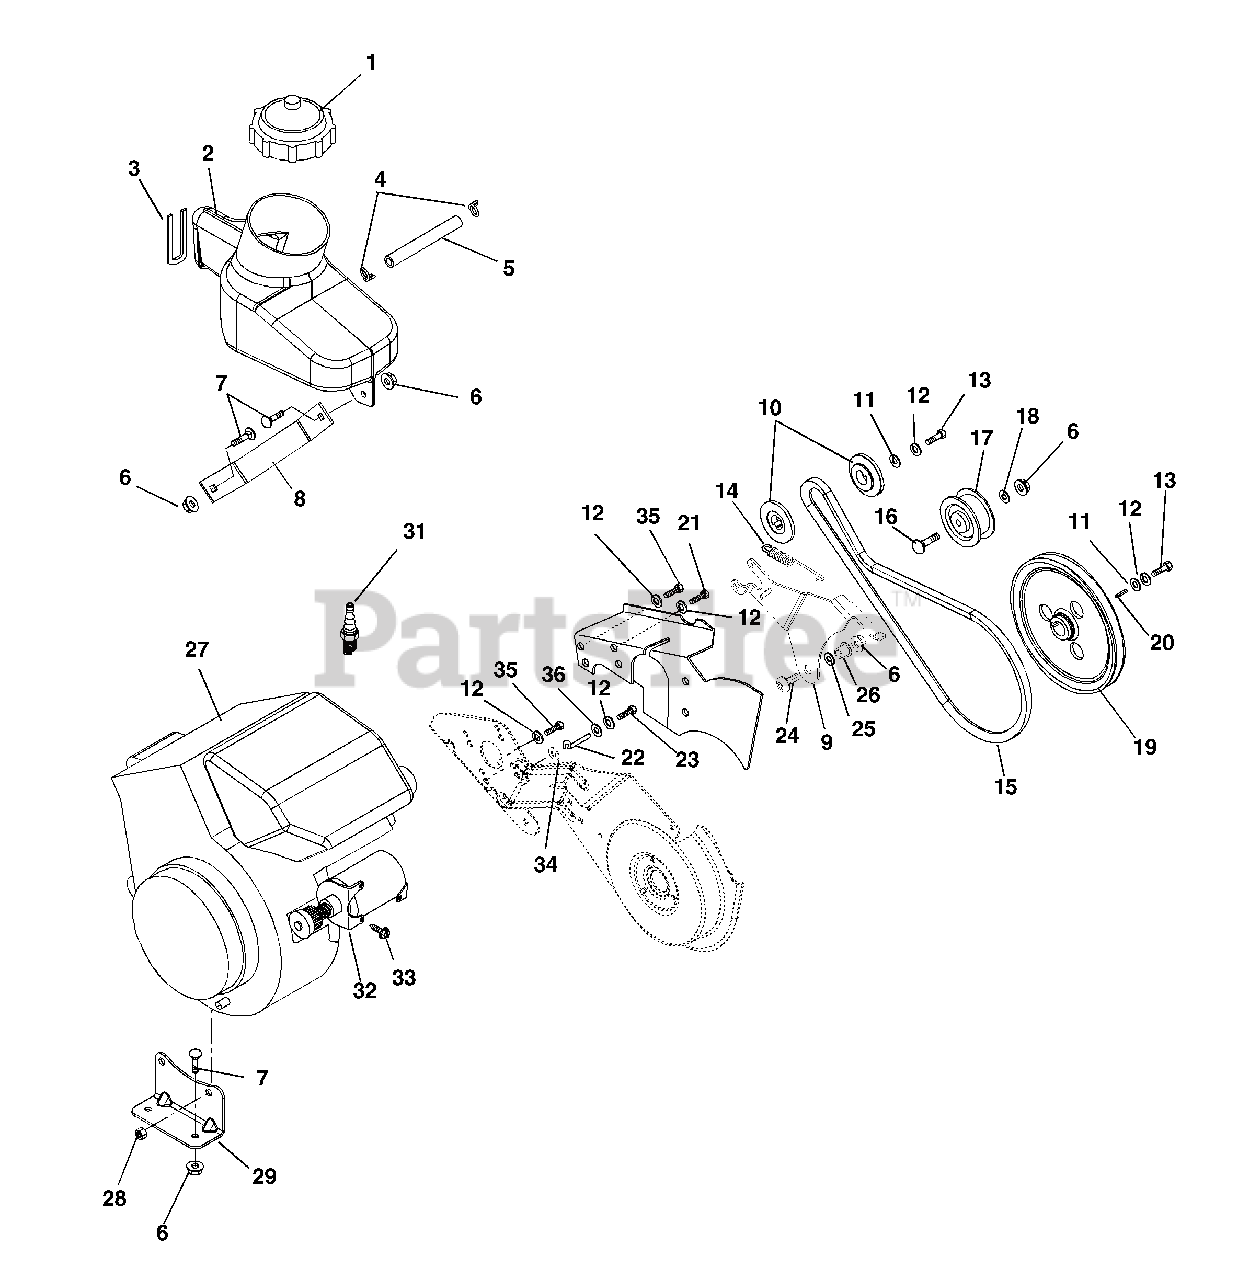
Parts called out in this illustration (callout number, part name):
1	CAP-FUEL
2	KIT, 938 FUEL TANK
3	TAPE FOAM,NEOPRENE
4	CLAMP-HOSE WIR.490/.510X.092#8
5	GAS LINE 1/4" I.D. X 9.5
6	NUT-LK-FLG .250-20 PL BLK
7	@BLT-RDHDSQNK .25-20X.75 G5YZ
8	BRKT-FUEL TANK MTG
9	ARM-IDLER
10	PLY-DRIVE 3LX 1.80 DIA
11	@WSHR-FL-STL.38X.875X.083 YWZC
12	WSHR-LK .312X.097 HVY YWZC
13	BLT-HEX .31-24X.75 YWZC GR5
14	SPRING, EXTENSION
15	V-BELT, 3L-RAW EDGE
16	@BLT-RDHDSQNK .25-20X1.25 G5YZ
17	IDLER-FLAT 1.75 X .27 DAYCO
18	WSHR-FL-STL .281X1.000X.063
19	PLY-V 5.50X.671 W/KEY "A"
20	KEY-SQ .188X.75X.188
21	SCR-CAP .31-18X.75 S/HD
22	FINGER-BELT
23	@BLT-HEX .31-18X1.00 GR5 YWZC
24	SCR-MCH .25-20X.75 TXTR YWZC
25	WSHR-FL-STL .505X.875X.024 YWZ
26	BSHG-FLG .265X.437X.250X.750
27	ENGINE, TH139SA 5HP 2CY TEC
28	@NUT-LK-CTR .31-18 YWZC
29	BRKT-ENGINE MTG
30	BAFFLE-BELT PROTECTIVE
31	PLUG, SPARK
32	MOTOR-STARTING
33	SCR-HFWH-TX-SEMS .25-20X.49 TE
34	@WSHR-LK-EXT.326X.599X.031YWZC
35	@BLT-HEX .31-18X.75 GR5 YWZC
36	@WSHR-FL-STL.344X.688X.065YWZC
